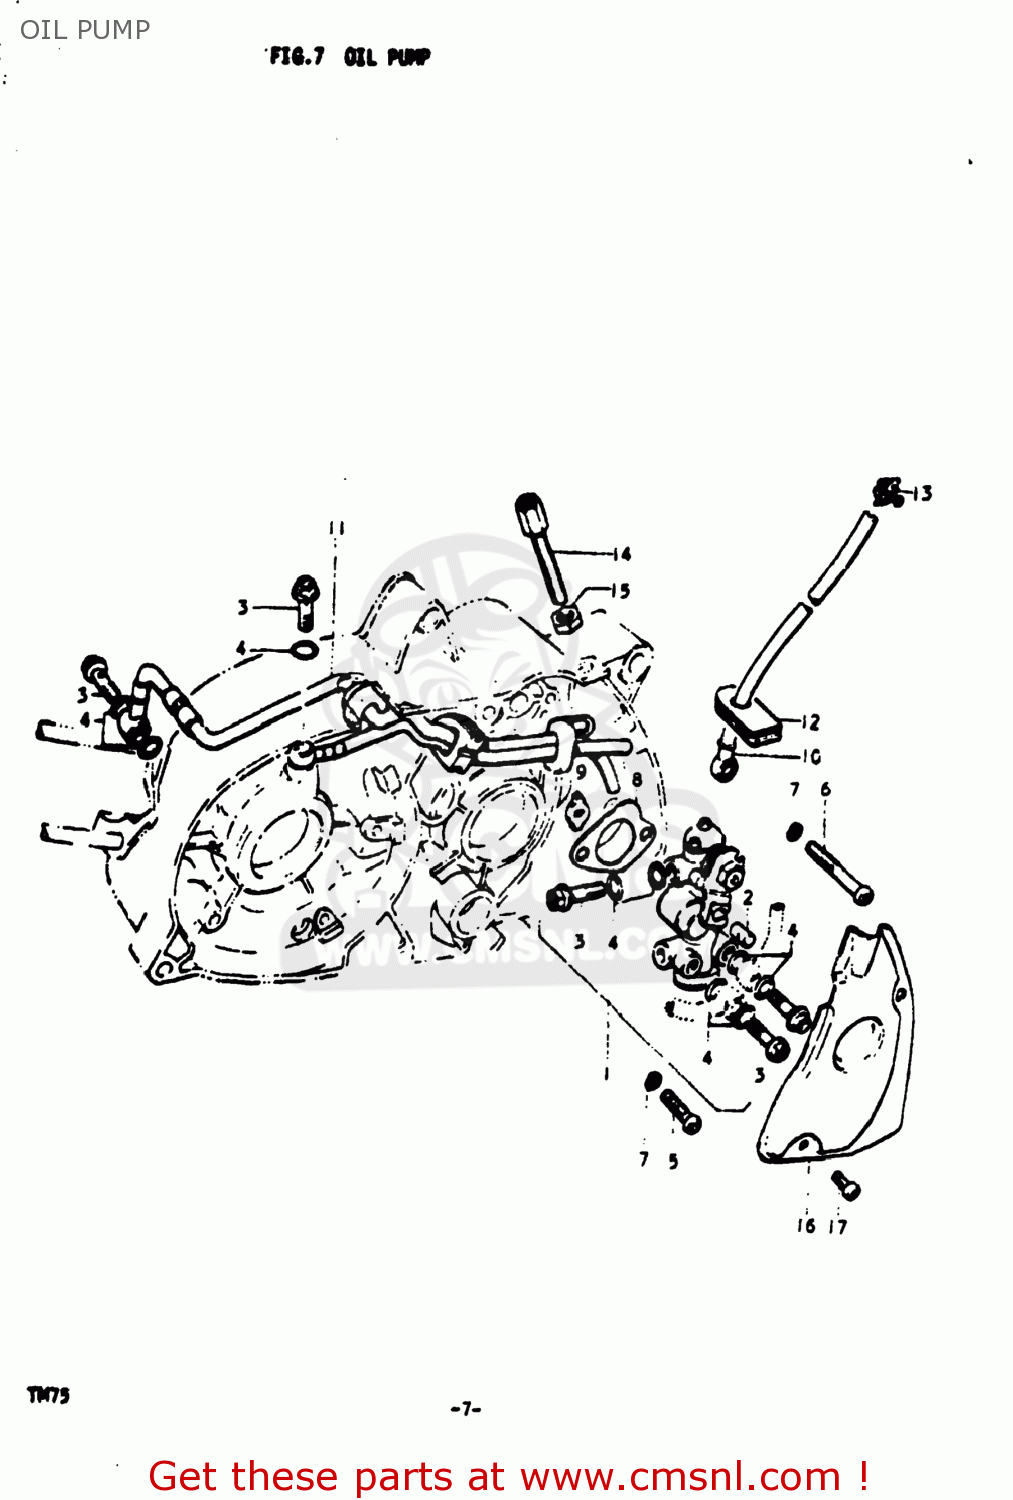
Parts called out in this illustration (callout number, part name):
1	PUMP ASSY,OIL
2	TERMINAL,CABLE
3	UNION BOLT
4	GASKET (NAS)
5	SCREW
6	SCREW
7	LOCK WASHER
8	GASKET,OIL PUMP (MCA)
9	PIECE,OIL PUMP DRIVE
10	HOSE,OIL NO.1
11	HOSE,OIL NO.2
12	GROMMET
13	CLAMP
14	BOLT
15	NUT
16	CAP,OIL PUMP INSPECTION
17	SCREW
